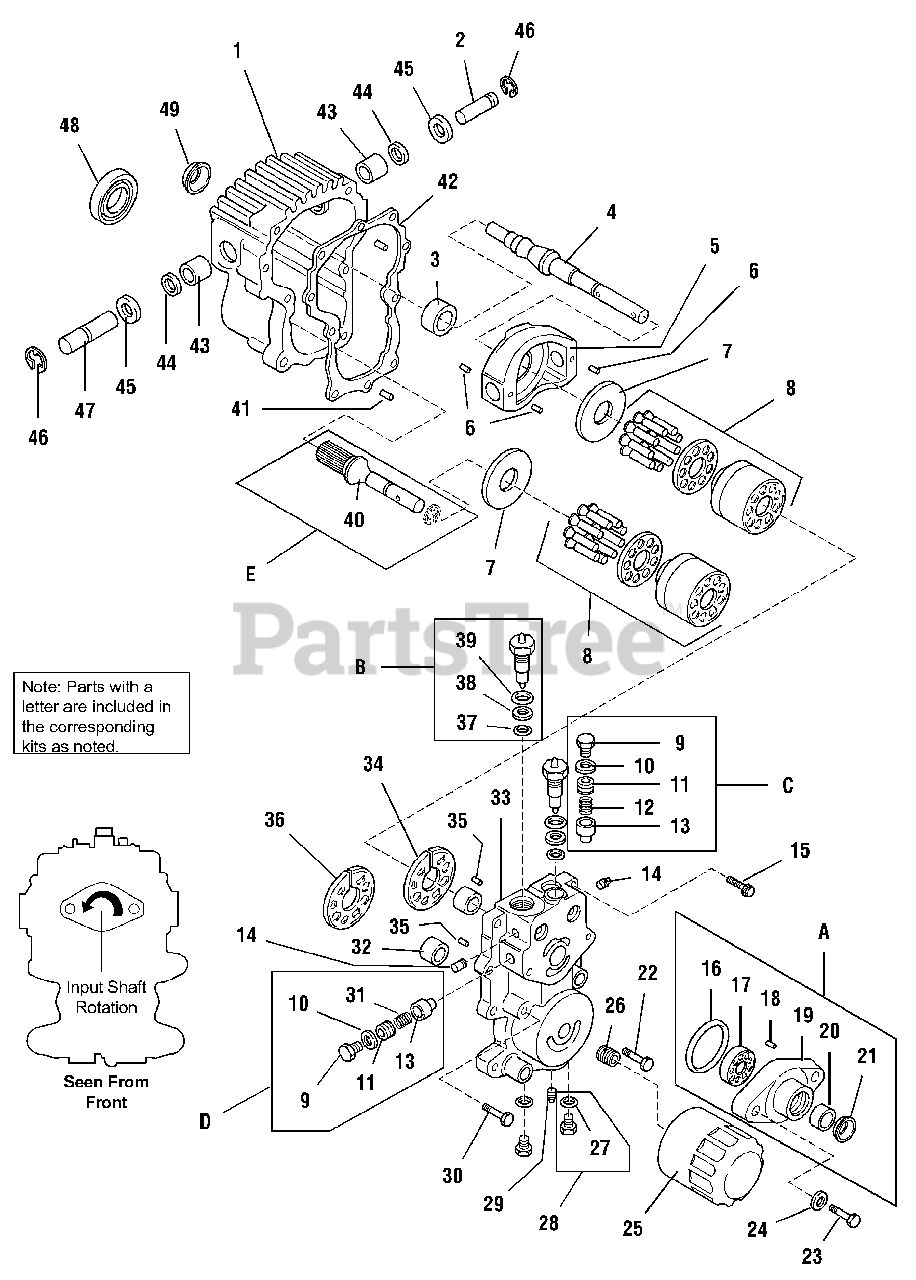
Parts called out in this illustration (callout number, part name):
1	HOUSING ASSY.
2	SHAFT, Trunnion
3	BEARING, Ball
4	SHAFT, Pump
5	PLATE, Swash
6	PIN, Spring
7	PLATE, Thrust
8	BLOCK, Cylinder
9	PLUG, Hex Hd.
11	KIT, Shim Pack
12	SPRING, Rel. Valve
13	CONE, Rel. Valve
14	PLUG, Pipe
15	CAPSCREW, 12 Pt.
18	PIN, Straight
19	HOUSING, Charge Pump
20	BEARING, Roller
22	CAPSCREW, Hex Hd, 3/6-16 x 1-1/4
23	CAPSCREW, Hex Hd, 7/16-14 x 2
24	LOCKWASHER, 7/16
25	FILTER, Oil
26	UNION, Filter
28	PLUG, Hex Hd.
29	PLUG, Pipe
30	CAPSCREW, Hex Hd, 3/8-16 x 2
31	SPRING, Rel. Valve
32	BEARING, Roller
33	SECTION, Center
34	PLATE, Valve (Pump)
35	PIN, Headless, Straight
36	PLATE, Valve (Motor)
38	RING, Back-Up
40	SHAFT, Motor (See Repair Kit "E")
41	PIN, Headless
43	BEARING, Needle
46	RING, Retaining
47	SHAFT, Trunnion
48	BEARING, Ball
A	CHARGE PUMP KIT
B	CHECK VALVE ASSY.
C	RELIEF VALVE KIT
D	RELIEF VALVE KIT
E	SHAFT & SNAP RING KIT
